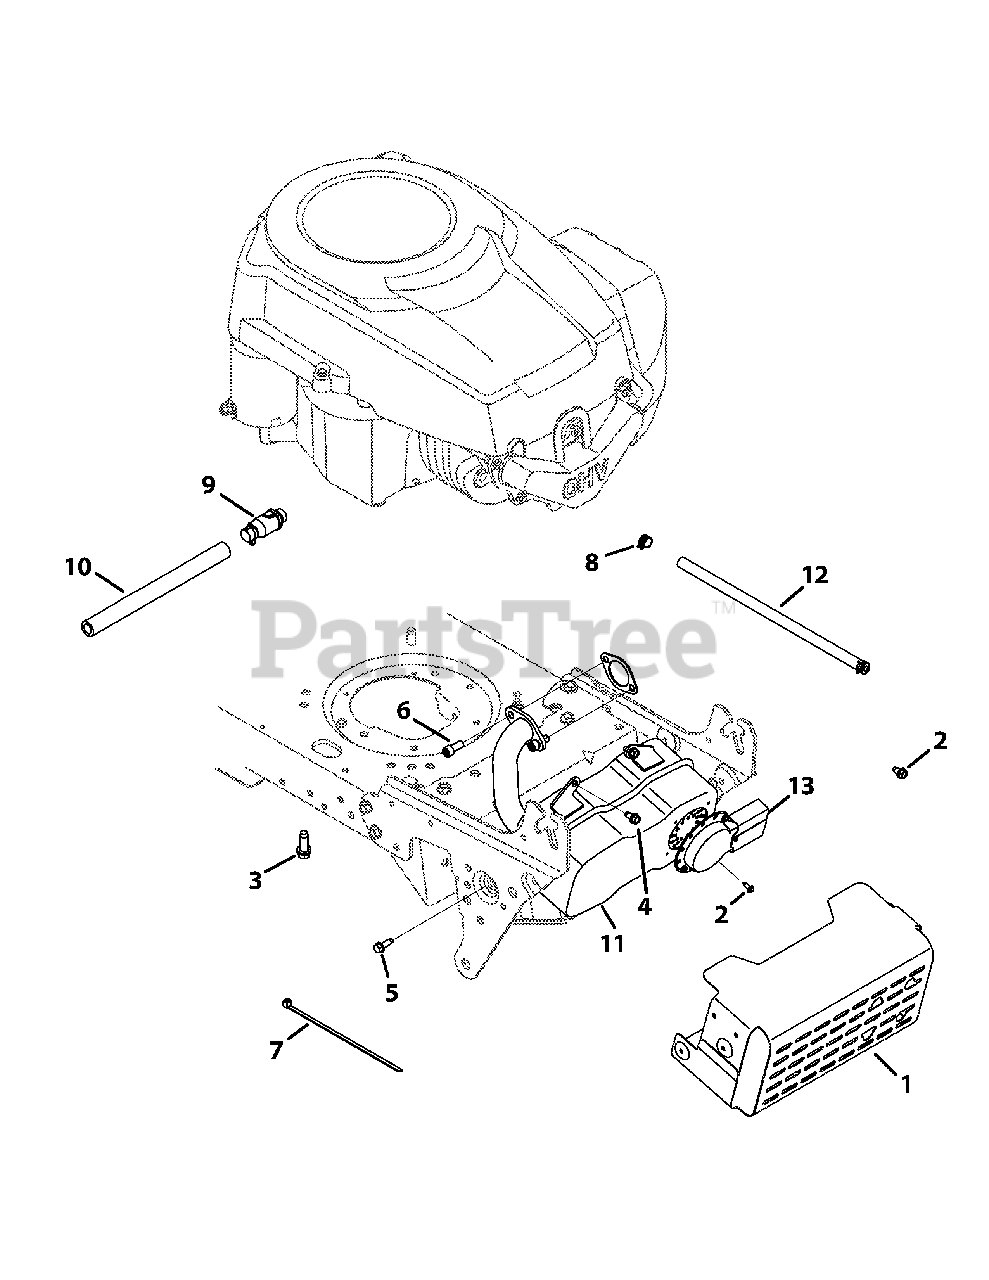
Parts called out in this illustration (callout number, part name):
1	Muffler Shield Assembly
2	Screw, 8-18 x .500
3	Screw, 3/8-16 x 1.0
4	Screw, 1/4-20 x .500
5	Screw, 1/4-20 x .750
6	Socket Screw, 5/16-18 x .750
7	Cable Tie
8	Clamp Hose, .490 diameter
9	Oil Drain
10	Oil Drain, Extension Hose
11	Muffler
12	Fuel Hose, Low Permeation
13	Muffler Deflector Long
